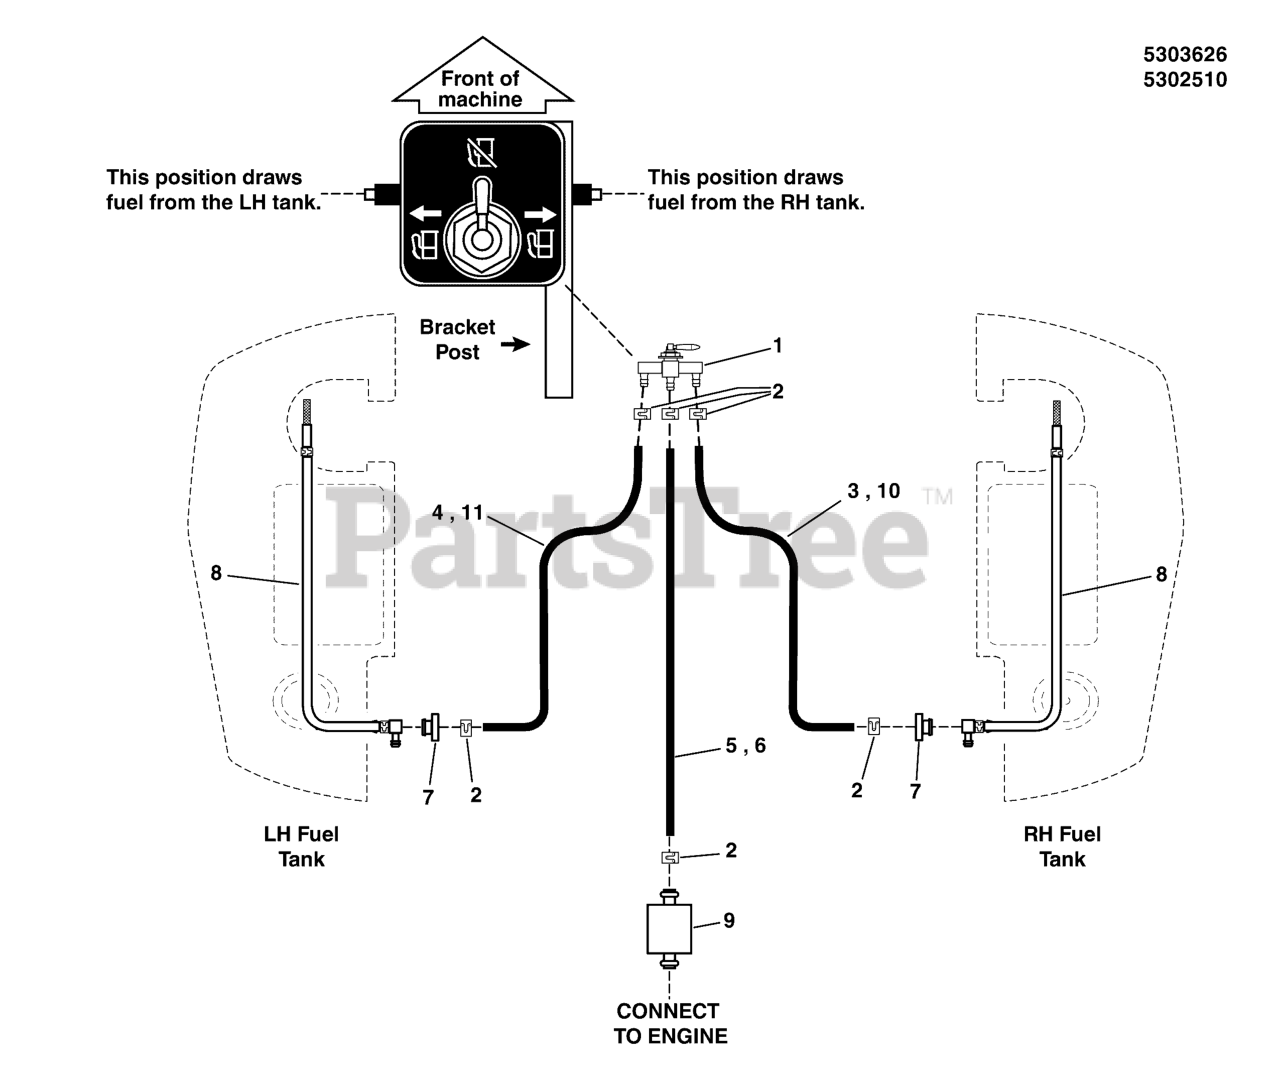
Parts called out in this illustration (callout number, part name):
1	VALVE, FUEL SHUT-OFF, 11772
2	CLAMP, HOSE, EXTERNAL, 1/2 - RED
3	HOSE, 1/4" FUEL, 27.00"
4	HOSE, 1/4" FUEL, 42.00"
5	HOSE, 1/4" FUEL, 21.00"
6	HOSE, 1/4" FUEL, 13.00"
7	BUSHING-FUEL TANK RED RUBBER
8	PICKUP TUBE ASM, FUEL TANK, 22"
9	FUEL FILTER (SV)
10	HOSE, 1/4" FUEL, 26.00"
11	HOSE, 1/4" FUEL, 35.00"
